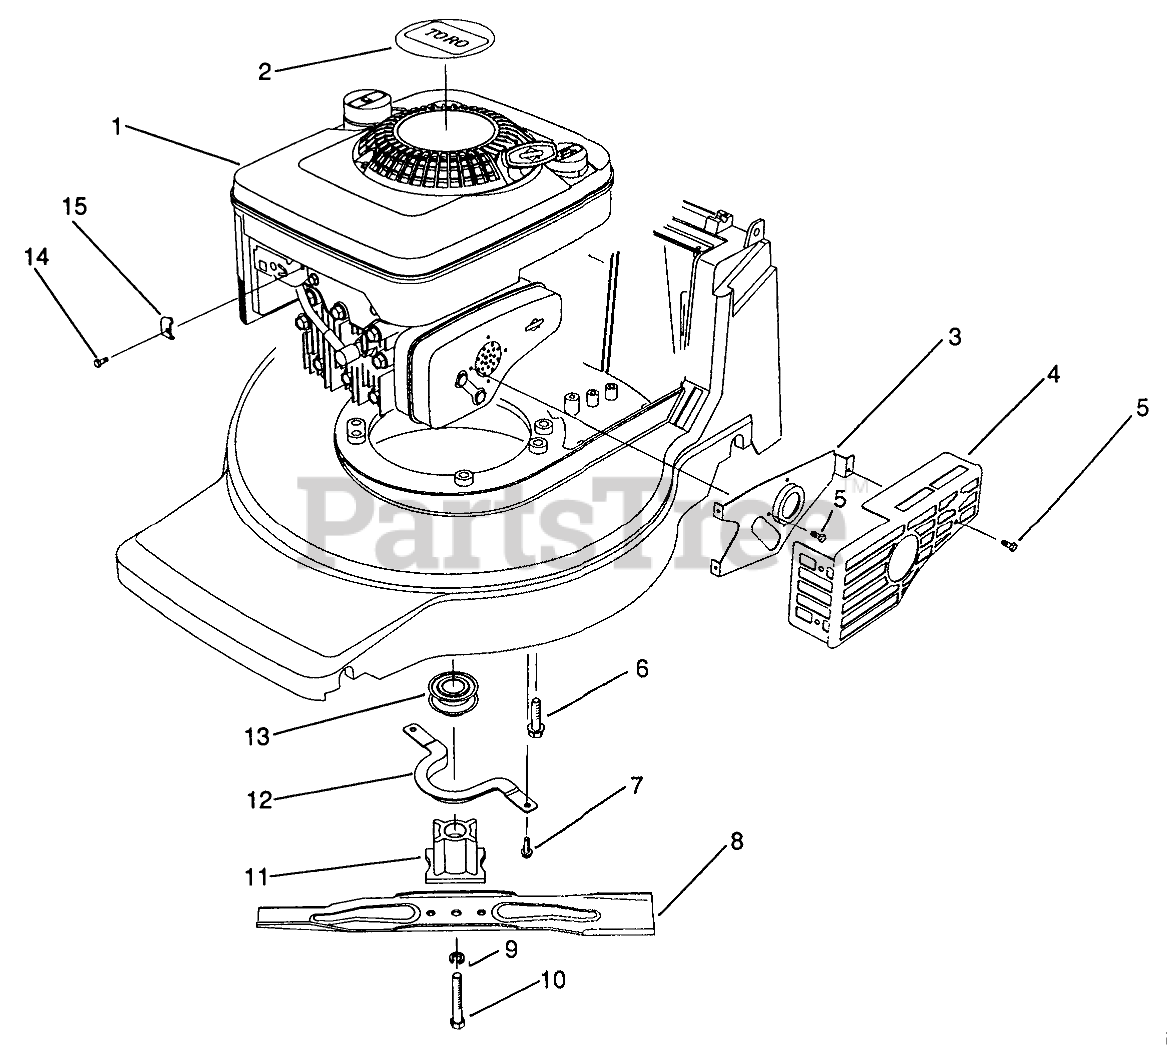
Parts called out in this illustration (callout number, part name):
1	Engine-B&S Quantum
2	DECAL - RECOIL
3	MUFFLER BRKT F/W
4	MUFFLER GUARD F/W
5	SCREW W/ENGINE
6	SCREW-HWH
7	SCREW-HWH
8	Blade-48cm
9	WASHER-LOCK
10	BOLT-BLADE
11	BLADE RETAINER - 25 MM
12	Guide-Belt
13	PULLEY-DRIVE, ZONE START
14	Screw
15	CLAMP-CASING
